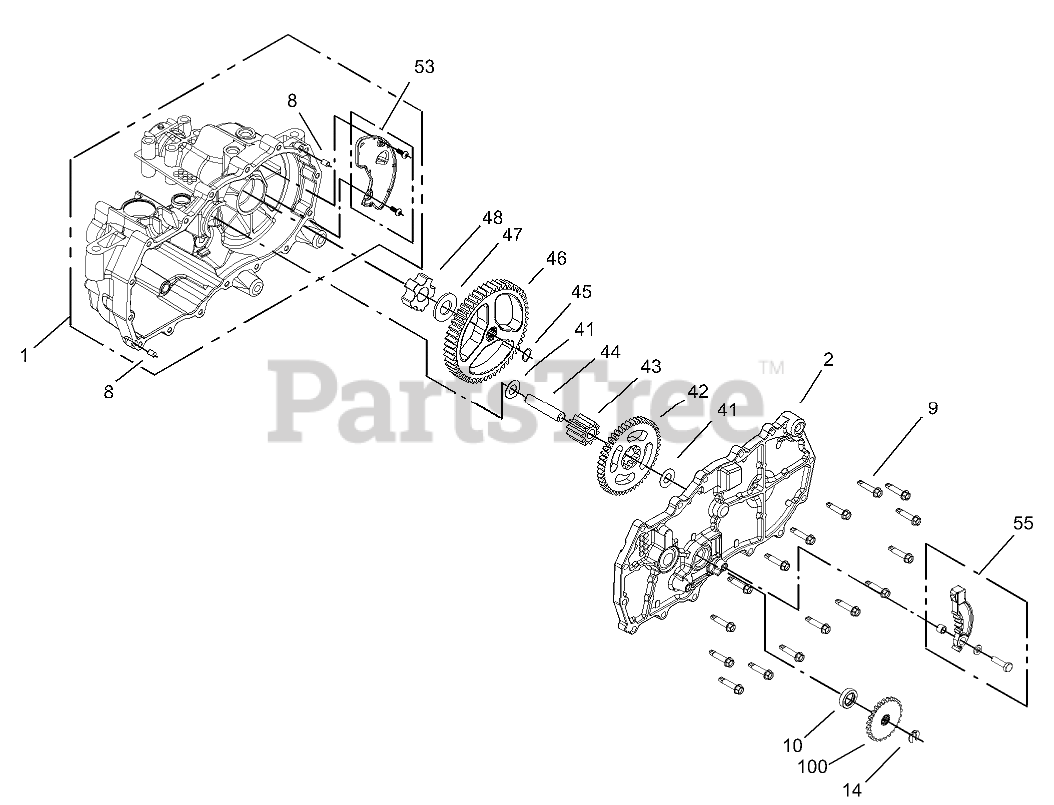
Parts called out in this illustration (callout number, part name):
1	MAIN HOUSING ASM
2	SIDE ASM
8	PIN-HYDROGEAR
9	SCREW-HHF
10	SEAL-OIL
41	WASHER
42	GEAR-10T/48T
43	GEAR-JACKSHAFT, 10T
44	PIN-JACKSHAFT
45	RING-RETAINING, SPIRAL
46	GEAR-BULL, 52T
47	WASHER
48	BEARING-SLEEVE
53	EXPANSION PLATE KIT
55	BRAKE ARM KIT
100	DISC-BRAKE, COG
